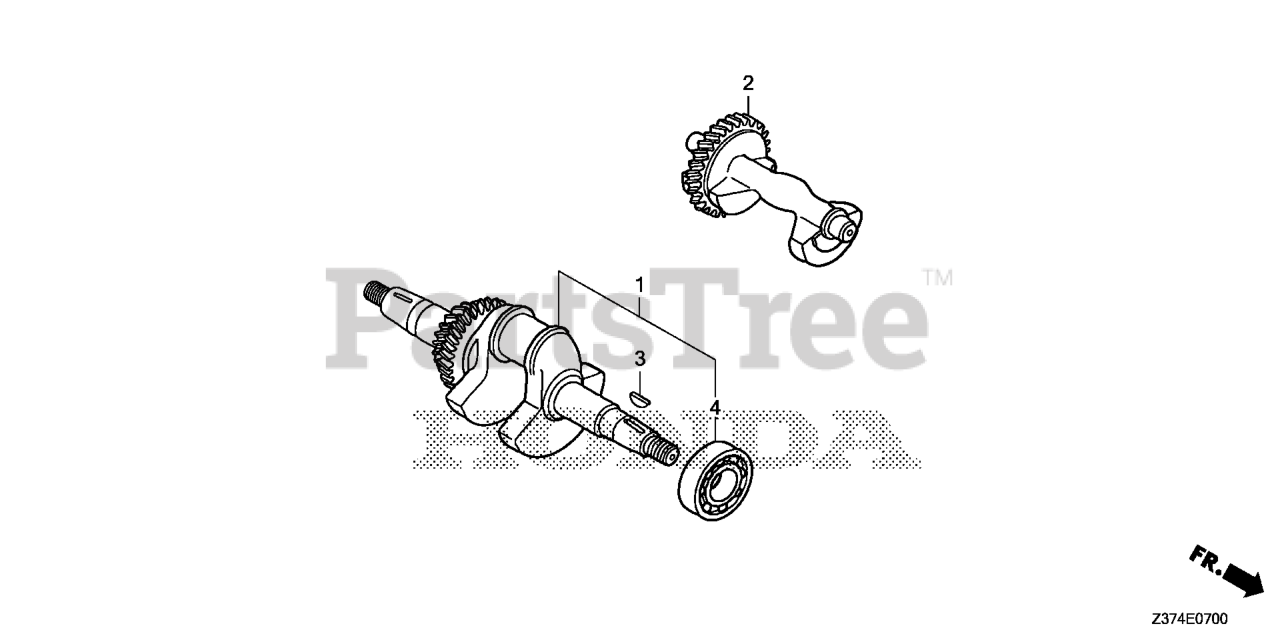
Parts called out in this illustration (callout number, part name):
1	CRANKSHAFT
2	WEIGHT, BALANCER
3	KEY, SPECIAL WOODRUFF (25X18)
4	BEARING, RADIAL BALL (6207SH)
